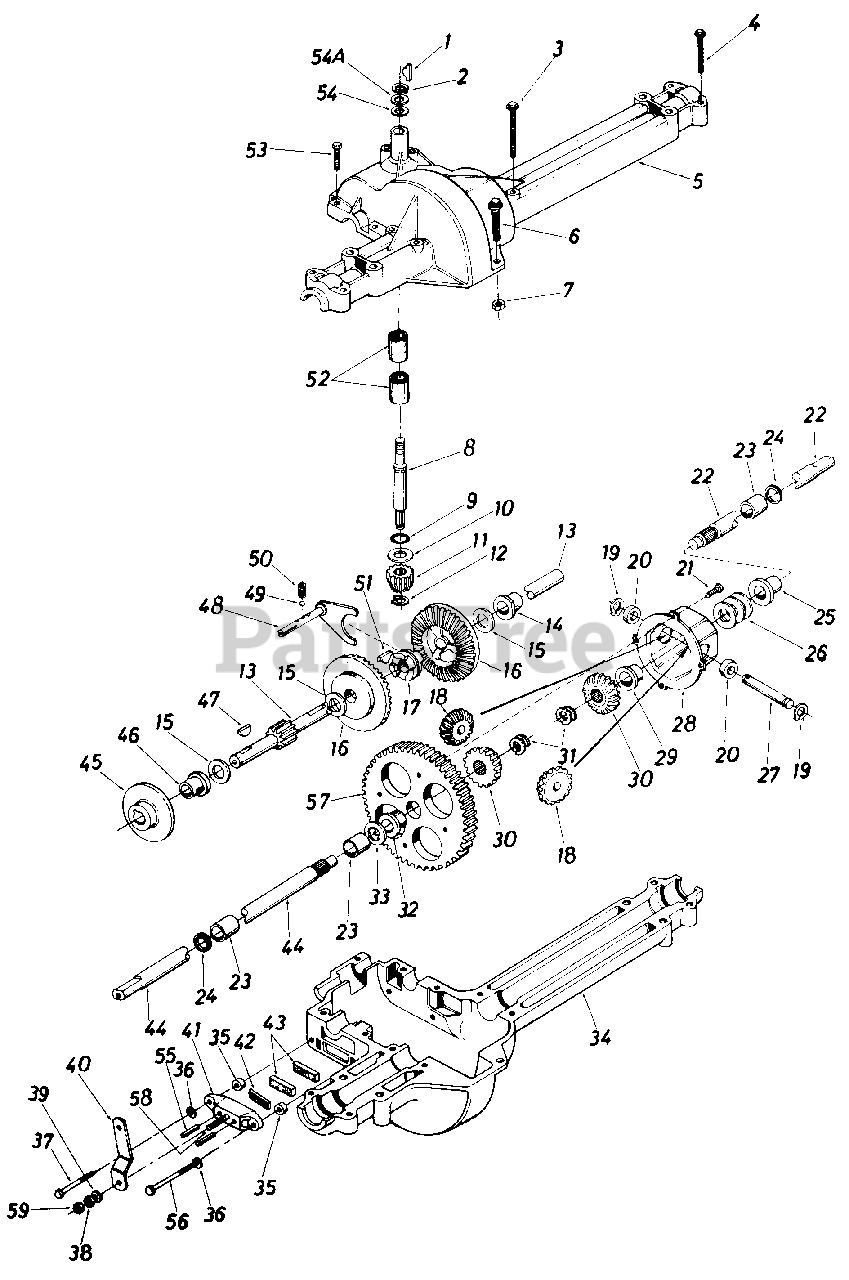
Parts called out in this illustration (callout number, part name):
1	#4 Hi-Pro Key 3/32 x 5/8" Dia.
2	Snap Ring .625" Shaft
3	Hex Bolt 1/4-20 x 1.75" Lg.
4	Hex Bolt 1/4-20 x 1.25" Lg.
5	Upper Housing
6	Hex Fl-Bolt 1/4-20 x .88" Lg.
7	Hex Jam Nut 1/4-20 Thd.
8	Input Shaft
9	Square Seal 5/8" I.D.
10	Thrust Washer 5/8" I.D. x 1.25" O.D.
11	Pinion Input 14T
12	Retaining Ring 7/16" Ext.
13	Drive Shaft
14	Flange Brg. 5/8" I.D. x 3/4" Lg.
15	Fl-Wash. 5/8" I.D. x 1.0" O.D.
16	Bevel Gear 42T
17	Clutch Collar
18	Miter Gear 1 5T
19	Snap Ring
20	Thrust Bearing 1/2" I.D. x 1.0" O.D.
21	Pan Head Scr. 1/4-20 x .50" Lg. w/Patch
22	Axle R.H.
23	Sleeve Bearing 3/4" I.D. x 1.0" Lg.
24	Oil Seal 3/4" I.D.
25	Flange Bearing 3/4" I.D. x 15/16" Lg.
26	Fl-Wash. .760" I.D. x 1.49" O.D.
27	Cross Shaft
28	Housing Differential
29	Flange Bearing 3/4" I.D. x .53" Lg.
30	Miter Gear
31	Retaining Ring
32	Flange Bearing 3/4" I.D. x .587
33	Fl-Wash. .760" I.D. x 1.49" O.D.
34	Lower Housing
35	Spacer .53" O.D. x 3/8" Lg.
36	L-Wash. 1/4" I.D.
37	Hex Bolt 1/4-20 x 1.50" Lg. Grade 5
38	Hex Nut 5/16-24 Thd.
39	Fl-Wash. .344" I.D. x .8751' O.D.
40	Actuating Arm
41	Brake Yoke
42	Puck Plate
43	Brake Puck
44	Axle L.H.
45	Brake Disc
46	Flange Bearing 5181' I.D. x 15/16" Lg.
47	Woodruff Key 3/16 x 5/8 HT
48	Shift Fork Ass'y.
49	Ball Detent.250" Dia.
50	Spring Detent
51	#9 Hi-Pro Key 3116" x 3/4" Dia. HT
52	Needle Brg. 5/8" I.D. x 1/2" Lg.
53	Hex Bolt 1/4-20 x 1.00" Lg.
54	Fl-Wash. 5/8" I.D. x .030
54A	Fl-Wash. 5/8" I.D. x .040
55	Actuating Pin 5/16" Dia.
56	Hex Bolt 1/4-20 x 1.50" Lg. Grade 5
57	Differential Gear 72T
58	Sq. Hd. Bolt 5/16-24 Thd.
59	Hex Jam Nut 5/16-24 Thd.
